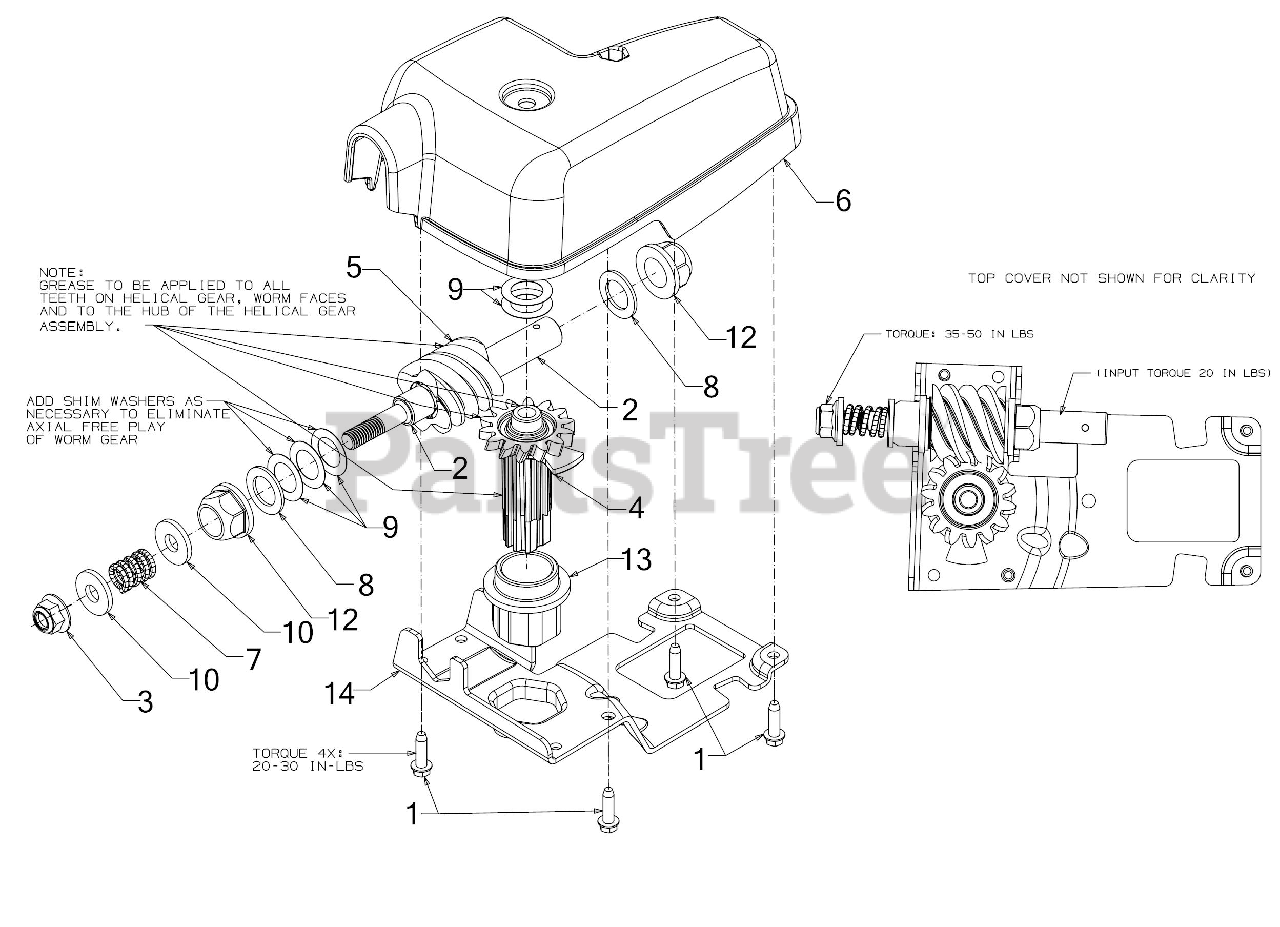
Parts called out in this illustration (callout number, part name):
1	SCREW #12-16 .75
2	WORM DRIVE SHAFT .625
4	HELICAL GEAR-14T
5	WORM GEAR
6	CHUTE GEARBOX COVER
7	COMPRESSION SPRING
8	FLAT WASHER
9	SHIM WASHER .632X1.000X.010:HD
12	FLANGE BEARING
13	HEX FLANGE BEARING
14	CHUTE ROTATION BRACKET
